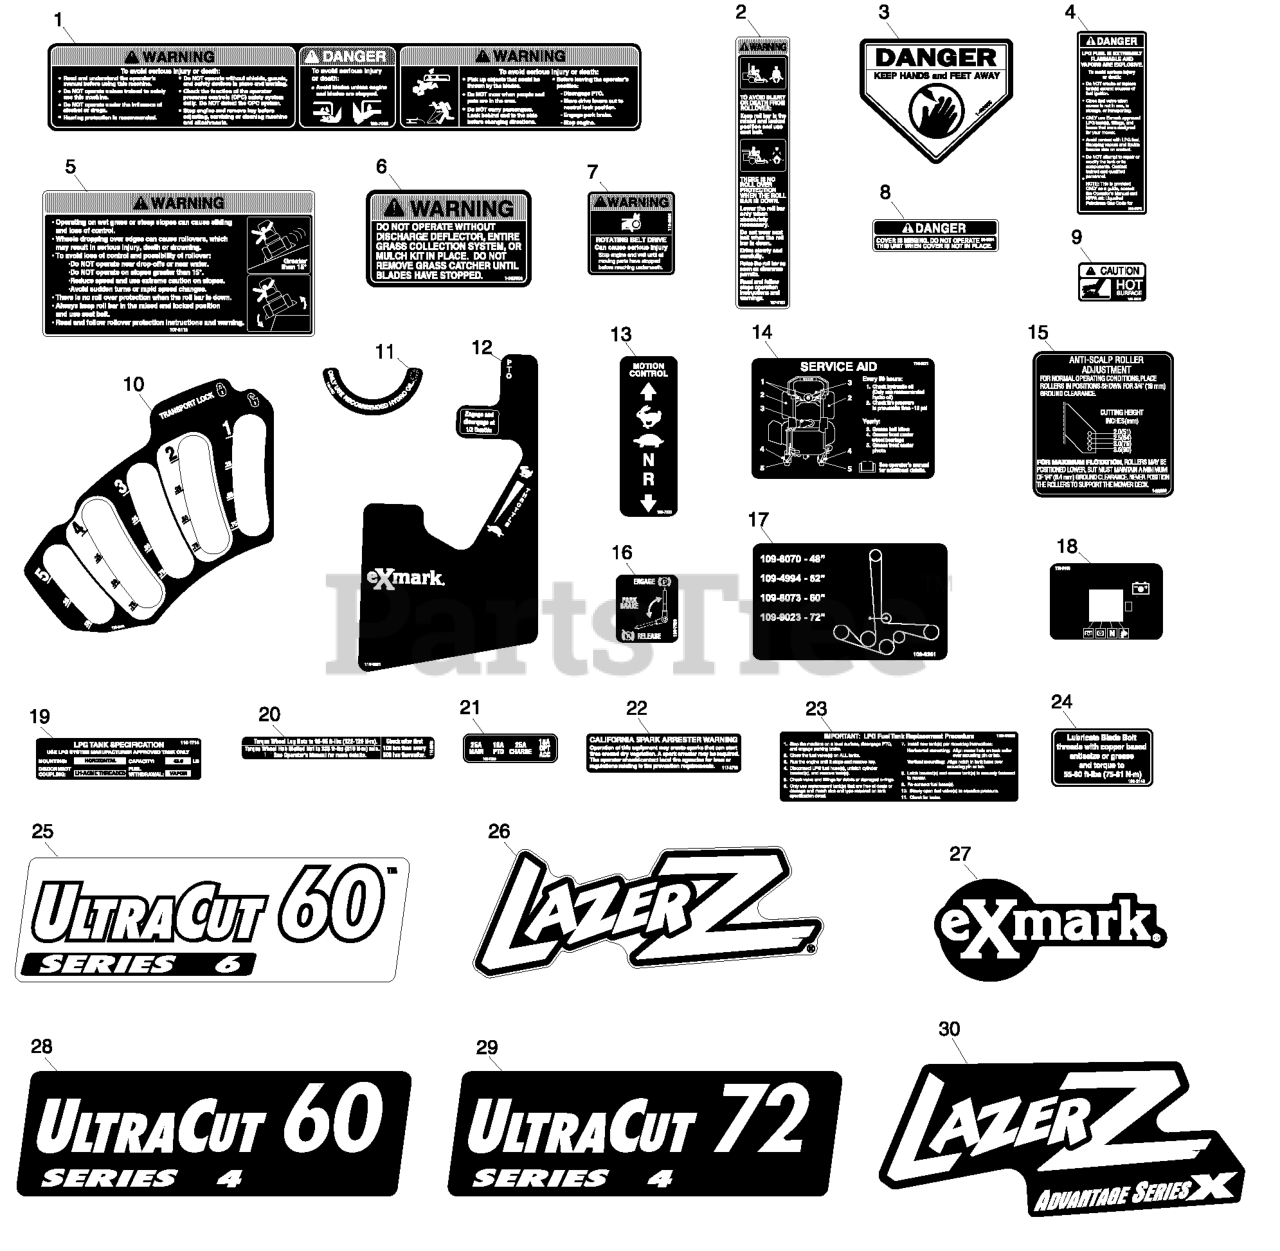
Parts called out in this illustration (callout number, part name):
1	DECAL-CONSOLE
2	DECAL-WARNING, FOLDING RO
3	DECAL-DANGER
4	DECAL-LPG WARNING
5	DECAL-WARNING
6	DECAL-WARNING, DISCHARGE
7	DECAL-BELT DRIVE
8	DECAL-COVER, MISSING
9	DECAL-CAUTION
10	DECAL-HOC
11	DECAL-HYDRO OIL
12	DECAL,CONTROL PANEL LP
13	DECAL-MOTION CONTROL
14	DECAL-SERVICE AID
15	DECAL,ANTISCALP
17	DECAL,BELT ROUTING
18	DECAL-METER, HOUR
19	DECAL-LPG 43.5LB TANK
21	DECAL-FUSE
22	DECAL-ARRESTER, SPARK
23	DECAL-TANK REPLACEMENT
24	DECAL,BOLT TORQUE
25	DECAL,ULTRACUT 60 SERIES
26	DECAL,LAZER MODEL
28	DECAL,ULTRACUT 60 SERIES
29	DECAL,ULTRACUT 72 SERIES
30	DECAL,LAZER ASX LOGO
